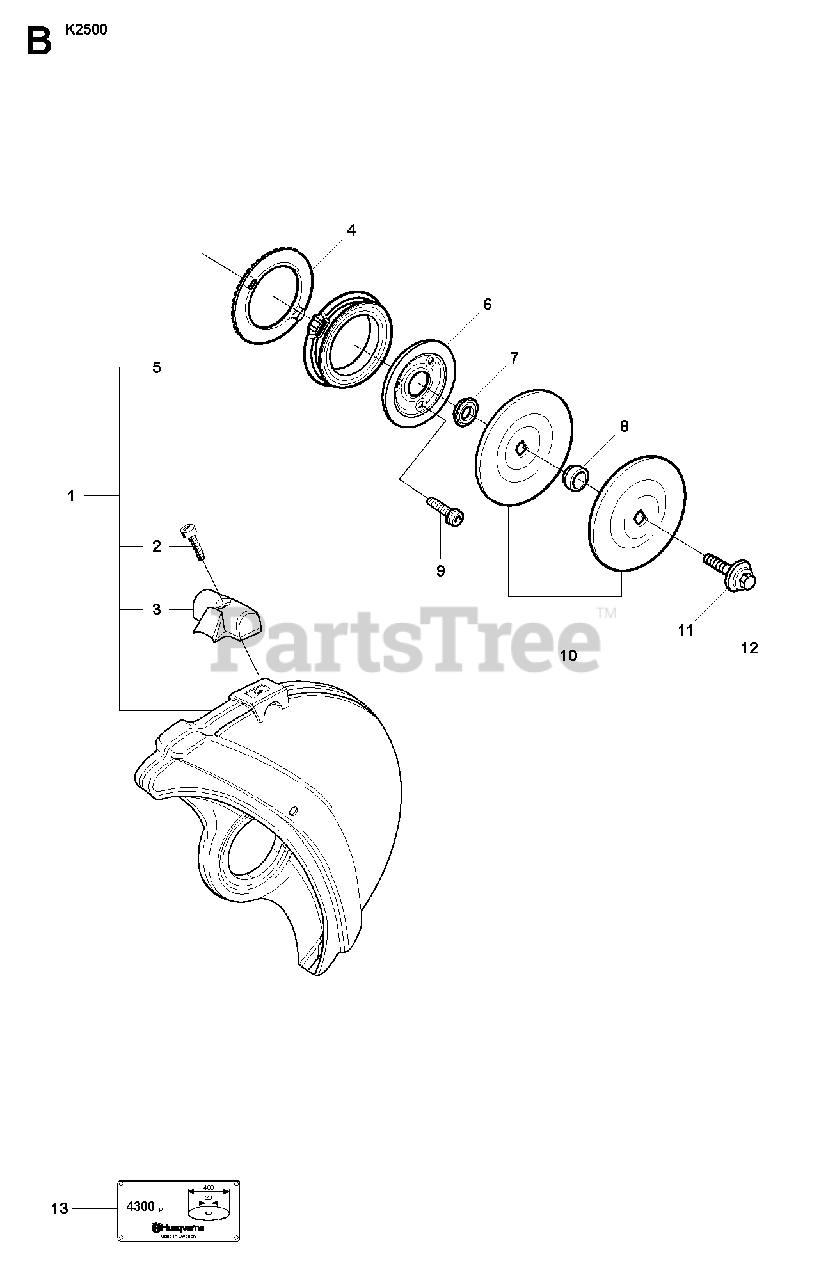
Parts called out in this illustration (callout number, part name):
1	WHEEL GUARDIncl. 2, 3, 5
2	SCREW IHSCM
7	SUPPORT FLANGE
8	KITDiam 20mm
8	KITDiam 22,2mm
8	KITDiam 25,4mm
8	BUSHINGDiam 30,5mm
10	FLANGE WASHERDiam 105mm
10	FLANGE WASHERDiam 119mm
13	LABELDiam 20mm
13	LABELDiam 25,4mm
